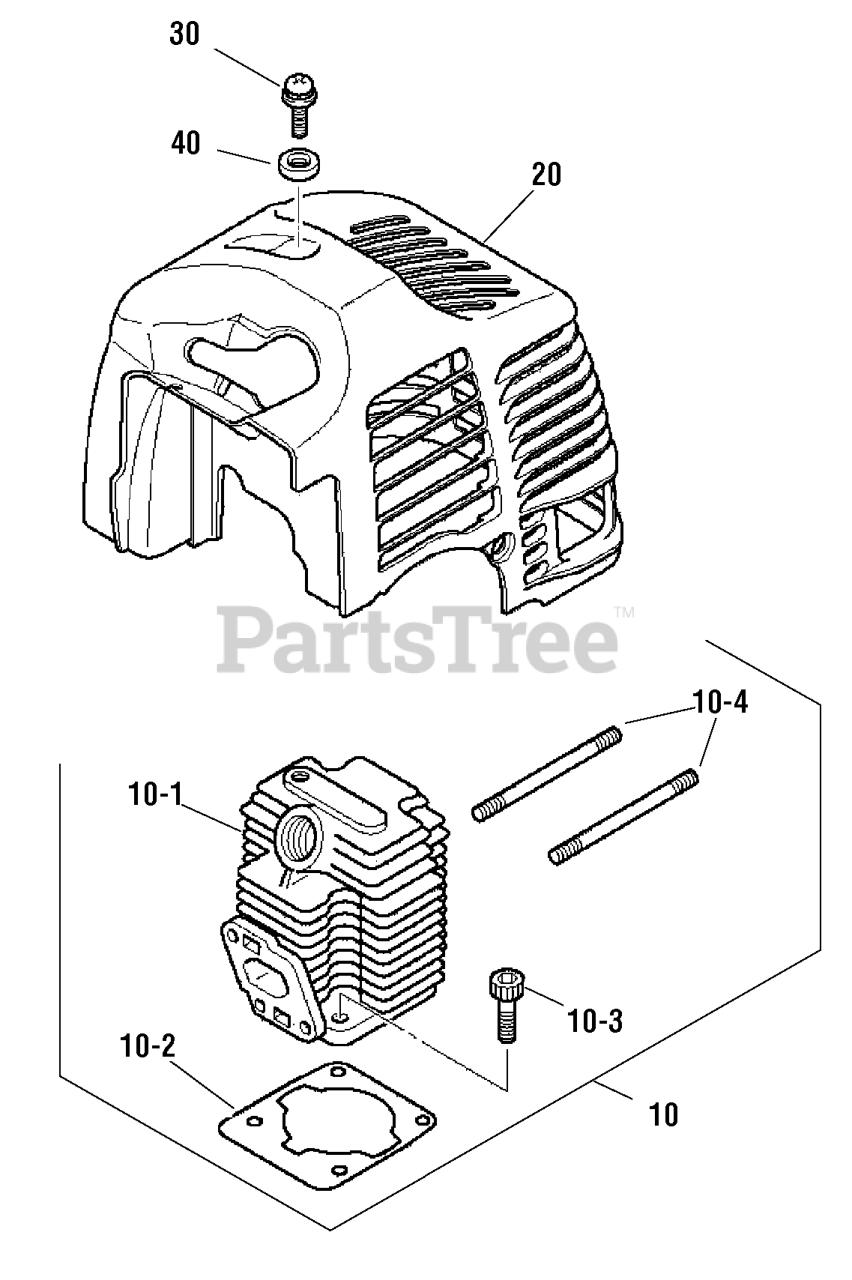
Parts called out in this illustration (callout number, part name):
10	CYLINDER ASSEMBLY
10-1	CYLINDER
10-2	GASKET, Cylinder
10-3	BOLT
10-4	BOLT
20	COVER, Top
30	SCREW & WASHER
40	WASHER
